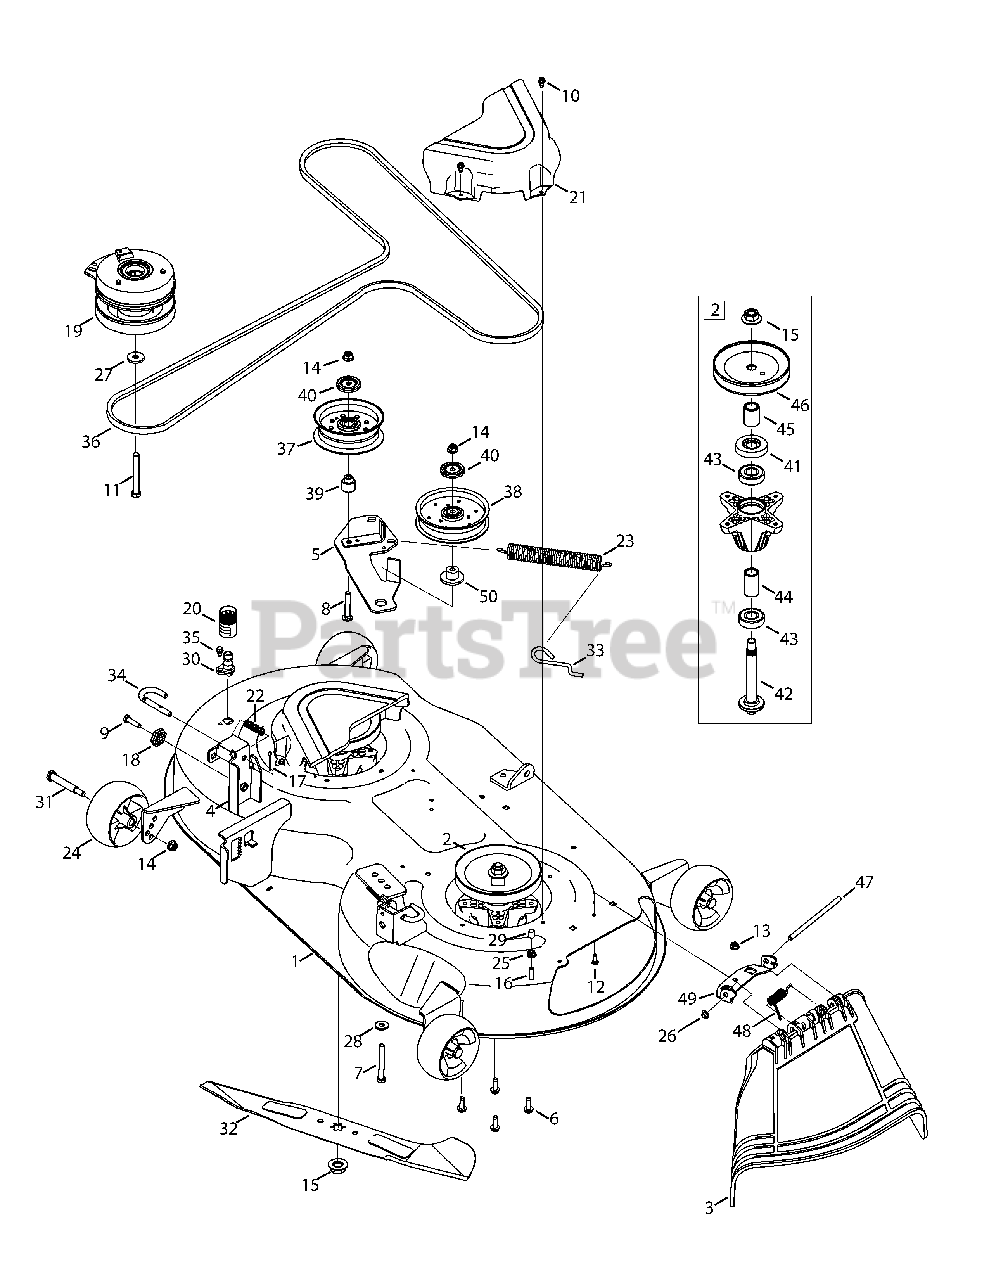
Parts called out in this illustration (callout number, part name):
1	46"Deck Assembly
2	Spindle Assembly
3	Chute Deflector Assembly
4	Deck Lift Bracket
5	Deck Idler Assembly
6	Hex Washer Screw, 5/16-18 x .750
7	Hex Cap Screw, 3/8-16 x 3.50
8	Carriage Screw, 3/8-16 x 2.00
9	Hex Flange Screw, 3/8-16
10	Hex Washer Screw, 1/4-20 x .625
11	Screw, 7/16-20 x 3.25
12	Hex Cap Screw, 1/4-20 x .62
13	Nut, Flange Lock, 1/4-20, Nylon
14	Flange Lock Nut, 3/8-16
15	Hex Flange Nut, 5/8-18
16	Hex Cap Screw, 5/16-18 x 1.00
17	Cotter Pin, 5/32 x 1.25
18	Deck Adjustment Gear
19	Electric PTO Clutch
20	Water Nozzle Adapter
21	Belt Cover
22	Compression Spring, .66 x 1.9
23	Extension Spring, 1.25 OD x 1.751
24	Deck Ball Wheel, 5.0
25	Flange Lock Nut, 5/16-18
26	Push Cap
27	Flat Washer, .450 x 1.25 x .164
28	Flat Washer, .406 x 1.00 x .105
29	Cap, .290 x .500
30	Deck Wash Nozzle
31	Shoulder Screw, .5 x 2.5 x 3/8-16
32	Blade, 2 in 1, 23.25
33	Deck Spring Rod
34	Deck Hanger Rod
35	Shoulder Screw, 1/4-20 x 0.50
36	V-Belt
37	Pulley, Idler, 4.50" Dia.
38	Idler Pulley, 5.00 Dia.
39	Shoulder Spacer
40	Pulley Cap
41	Bearing Shield
42	Spindle Shaft
43	Ball Bearing
44	Spacer, .792 x 1.060 x 1.860
45	Spacer, .8 x 1.1 x 2.26
46	Deck Pulley
47	Hinge Pin
48	Spring, Torsion, .440 ID x 1.75
50	Shoulder Spacer
